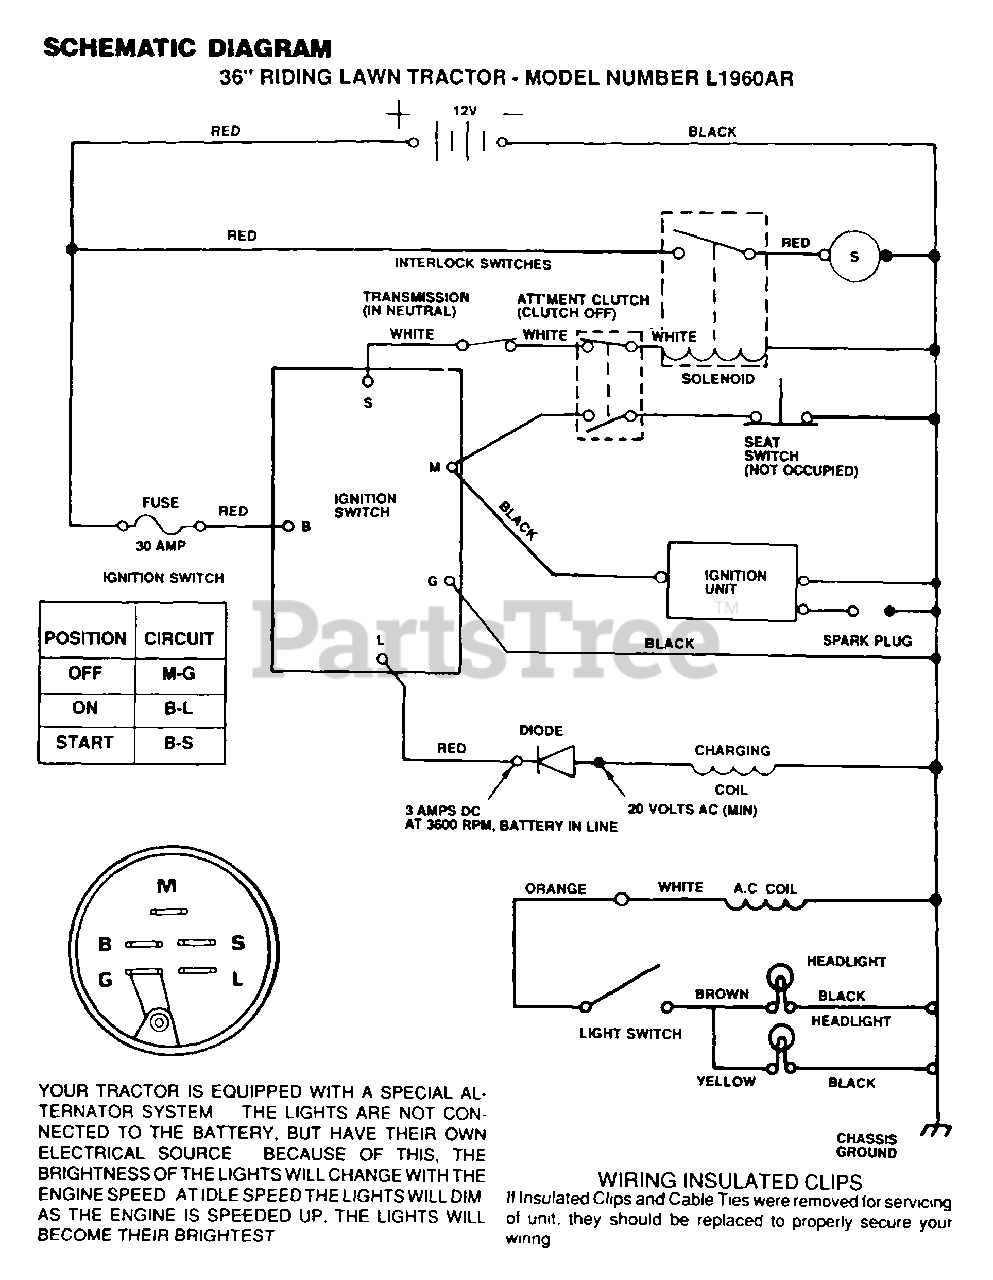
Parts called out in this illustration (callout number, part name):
1	HOUSING UPPER
3	BALL DETENT
4	SPRING, DETENT
5	SCREW, SET
6	ASSY SHIFTER
8	WASHER PLAIN
9	RING RETAINING
10	RING RETAINING
11	WASHER PLAIN
11	WASHER, PLAIN .632 X 1.00 X .026
11	WASHER, PLAIN .632 X 1.00 X .060
13	WASHER, PLAIN .632 X 1.38 X .046
14	KEY WOODRUFF #9
15	ASSY KIT INPUT SHAFT
16	PINION, BEVEL, 14 TEETH
17	RING, RETAINING
18	CHAIN, 24 PITCHES
19	BEARING, FLANGE
20	GEAR SPUR, 14 TEETH
21	COLLAR CLUTCH
22	KEY CLUTCH
23	KEY WOODRUFF #3
24	SHAFT INTERMEDIATE
25	KEY, WOODRUFF, #61
26	RING, RETAINING
27	SPROCKET, 18 TEETH
29	GEAR, SPUR, 37 TEETH
30	GEAR, SPUR, 35 TEETH
31	GEAR, SPUR, 30 TEETH
32	GEAR, SPUR, 25 TEETH
33	GEAR, SPUR, 22 TEETH
35	WASHER, PLAIN .640 X 1.37 X .061
36	WASHER, PLAIN .632 X 1.00 X .026
37	SPACER .630 X 1.00 X .169
38	ASSY GEAR COMB 12&35 TEETH
39	SHAFT IDLER
40	SPACER .635 X .875 X .755
41	SPROCKET, 9 TEETH
42	GEAR, BEVEL, 42 TEETH
43	WASHER PLAIN
43	WASHER, PLAIN .758 X 1.25 X .031
44	SHAFT, DRIVE
45	GEAR, SPUR, 12 TEETH
46	GEAR SPUR, 15 TEETH
47	GEAR, SPUR, 20 TEETH
48	GEAR, SPUR, 25 TEETH
49	GEAR, SPUR, 28 TEETH
50	GEAR, SPUR, 31 TEETH
51	WASHER, PLAIN .632 X 1.00 X .060
53	WASHER PLAIN
54	AXLE LEFT HAND
55	GEAR, MITER, 15 TEETH
56	RING, RETAINING
57	GEAR, SPUR, 32 TEETH
58	SHAFT, CROSS
59	GEAR, MITER, 15 TEETH
60	AXLE, R.H.
61	HOUSING LOWER
62	PUCK, FRICTION
63	DISC, BRAKE
65	JAW, BRAKE
66	PIN, DOWEL
67	SCREW TAPPING
68	LEVER, ACTUATING
69	WASHER, PLAIN .321 X 1.00 X .055
70	BRACKET, ANTI-ROTATION
71	LOCKNUT 5/16-24
72	SCREW TAPPING
73	WASHER PLAIN
74	PUCK, FRICTION
